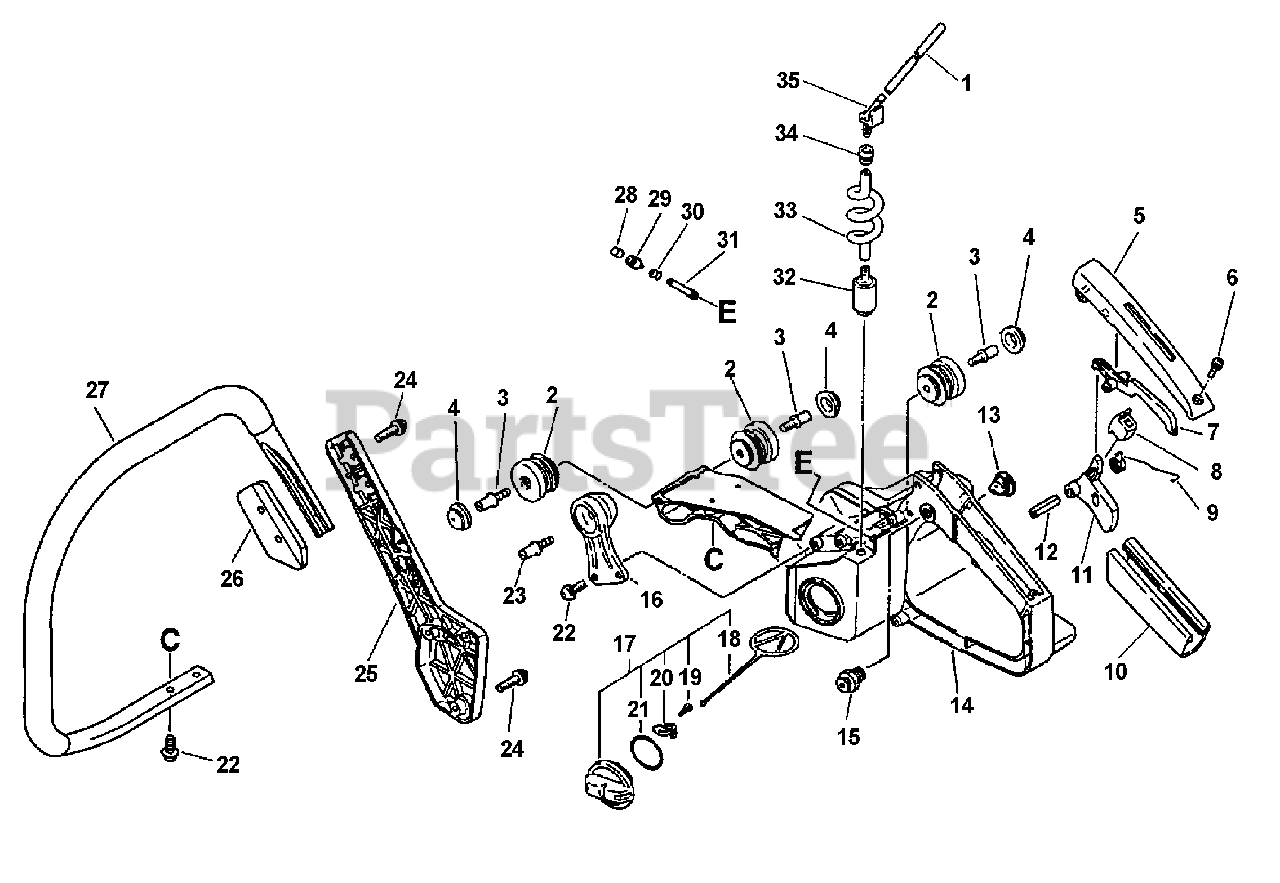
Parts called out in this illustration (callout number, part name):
1	PIPE, FUEL - 3×6×100
4	CAP, CUSHION
5	COVER, HANDLE
6	SCREW 4×14
7	LEVER, THROTTLE LOCKOUT
8	CUSHION, THROTTLE
9	SPRING, THROTTLE RETURN
11	TRIGGER, THROTTLE - ORANGE
12	PIN, SPRING Ø5×25 MM
14	HANDLE - REAR
15	LOCK, THROTTLE TRIGGER
17	CAP ASSY, FUEL
18	CONNECTOR, CAP L= 60 MM
19	SCREW, TAPPING 3×8
20	RETAINER, CONNECTOR
21	O-RING 29
22	BOLT 5×14
24	SCREW 5×20
25	BRACKET, GRAY HANDLE
26	BRACKET, HANDLE
27	HANDLE, FRONT
28	VENT ASSY
29	HOLDER, VENT
31	PIPE, VENT
32	FILTER, FUEL
33	PIPE, FUEL
34	GROMMET
35	CONNECTOR, PIPE
